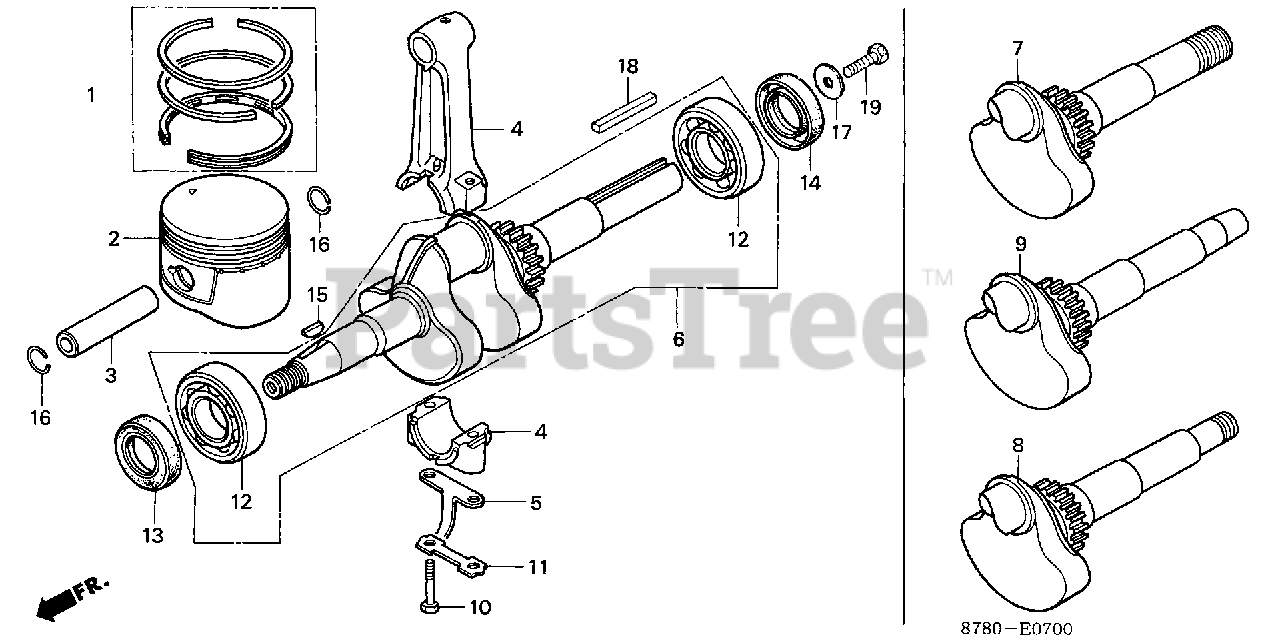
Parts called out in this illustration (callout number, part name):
1	RING SET, PISTON (STD)
1	RING SET, PISTON (0.25)
1	RING SET, PISTON (0.50)
1	RING SET, PISTON (0.75)
2	PISTON (STD)
2	PISTON (0.25) (NOT AVAILABLE)
2	PISTON (0.50)
2	PISTON (0.75)
3	PIN, PISTON
4	ROD, CONNECTING
4	ROD, CONNECTING (UNDER SIZE)
6	CRANKSHAFT
10	BOLT, HEX. (6X37)
11	WASHER, TONGUED
12	BEARING, RADIAL BALL (62/22)
13	OIL SEAL (22X35X6)
14	OIL SEAL (22X41X6)
15	KEY, WOODRUFF (25X14)
16	CLIP, PISTON PIN (15MM)
